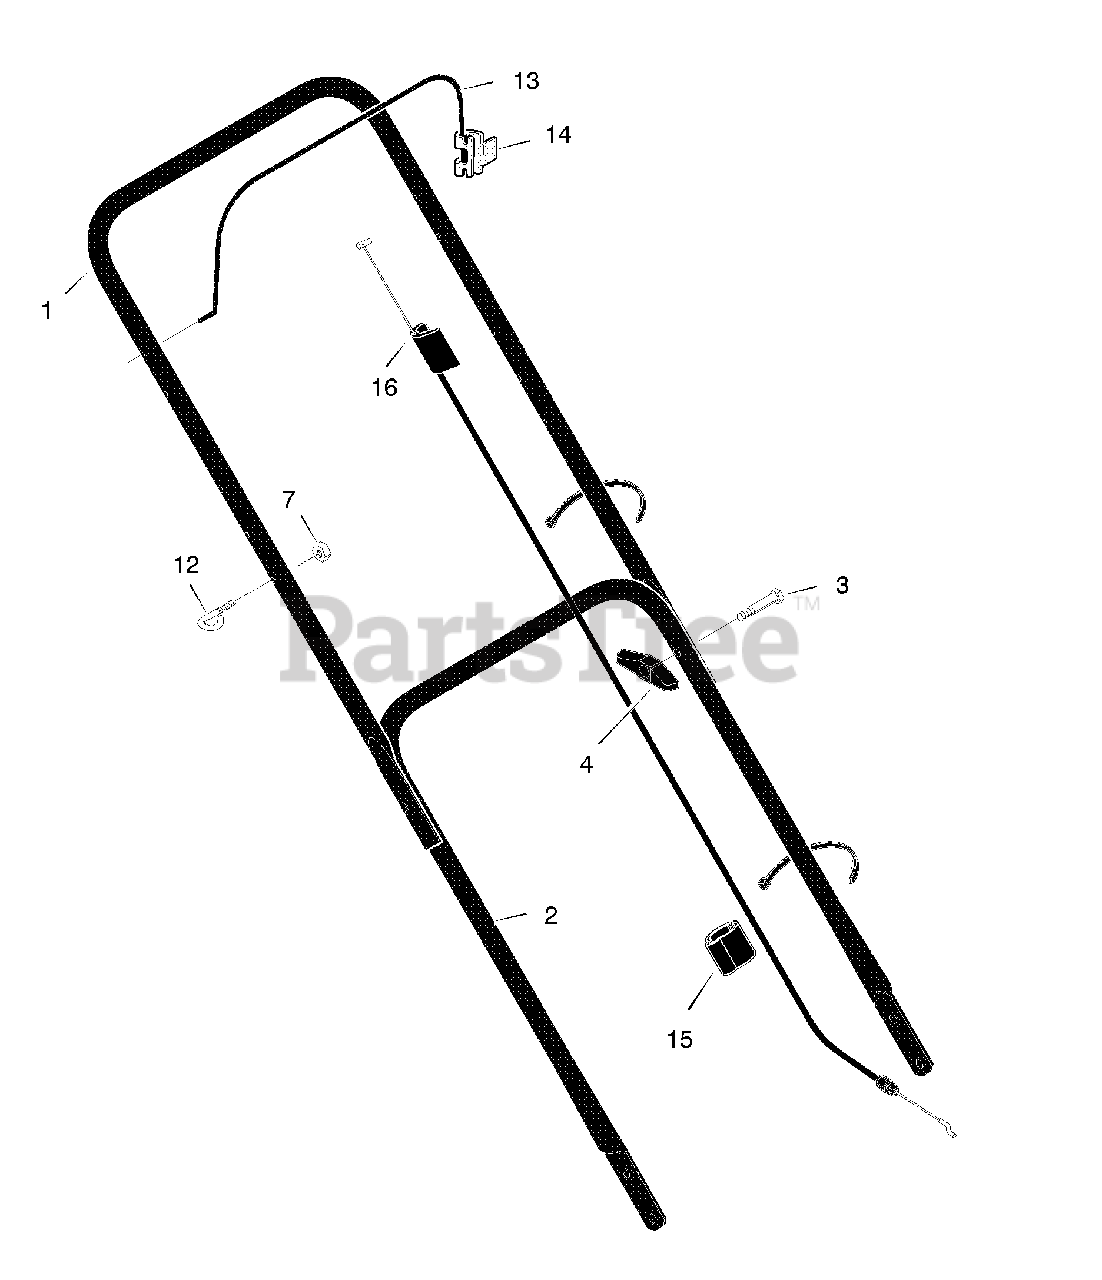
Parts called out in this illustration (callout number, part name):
1	Handle, Upper (Black)
2	Handle, Lower (Black)
4	Knob, Plastic
7	Locknut
12	Guide, Rope
13	Engine Stop Lever
14	Bracket, Stop Lever
15	Fastener, Cable
16	Engine Stop Cable
